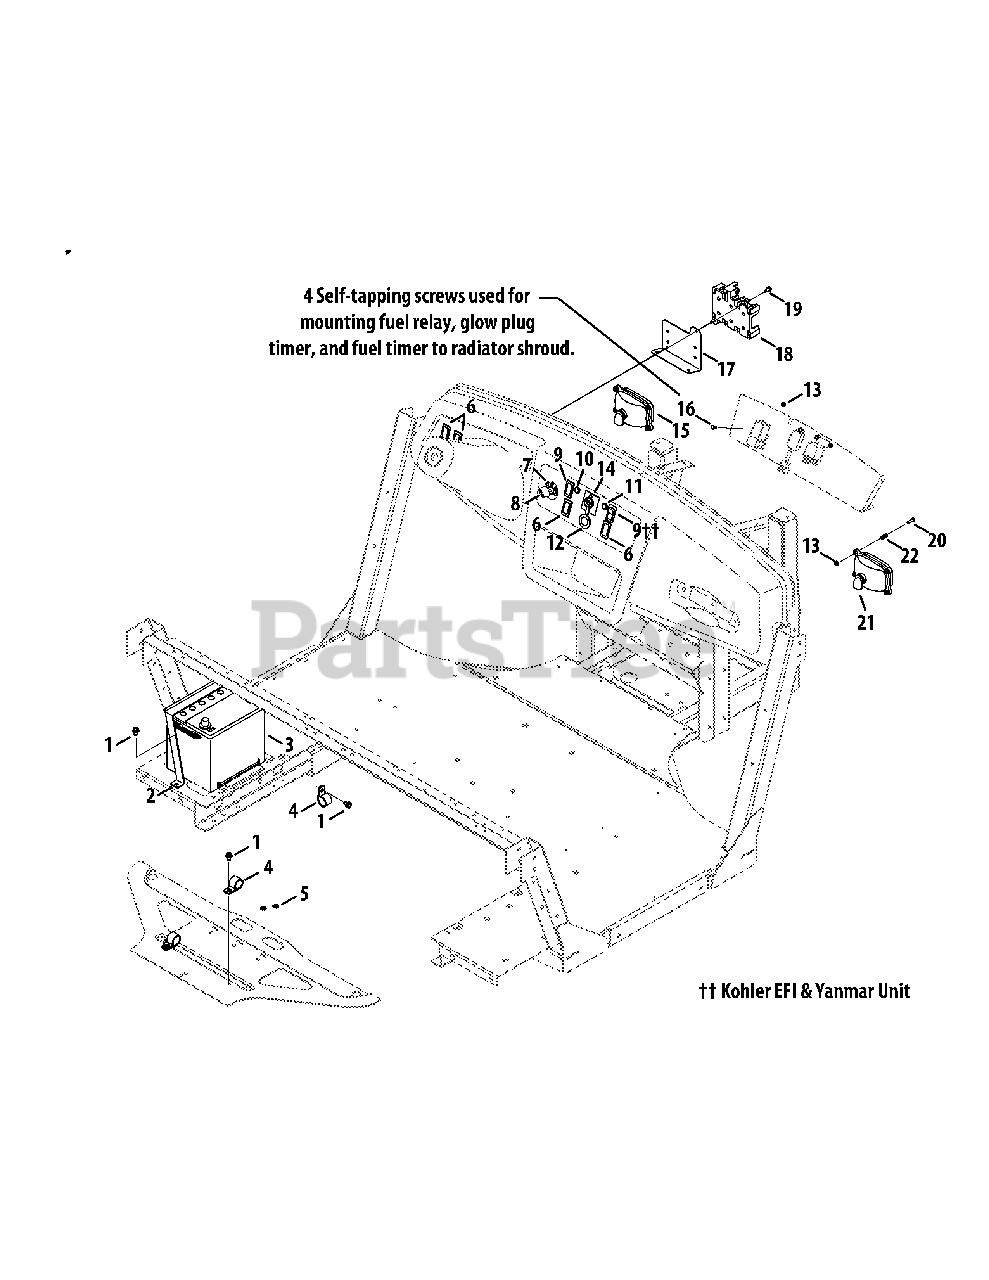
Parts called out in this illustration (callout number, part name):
1	Screw, TT, 5/16-18 x .500
2	Bracket, Mt., Battery
3	Battery, 450 CCA Wet
5	Washer, Lock, 5/16
6	Panel, Plug, Switch
7	Switch, Key, 4 Pos. Delta
8	Key, Delta, Plastic
9	Switch, 4x4, Rocker
10	Light, Ind., Yellow, LED
10	Lamp, Ind., Green, Incandescent
11	Light, Ind., Red, LED
11	Lamp, Ind., Red, Incandescent
12	Receptacle, Power, 12v
13	Nut, Hex Lock, #10-24
14	Meter, Ind., Hour Flat Face
15	Headlight Assembly (Incl. # 21)
16	Screw, #10-24 x .500
17	Bracket, Fuse Mount
18	Relay, Holder, 3-Way
19	Screw, TT, 1/4-20 x .500
20	Screw, TT, #10-24 x .750
21	Head lamp Bulb
